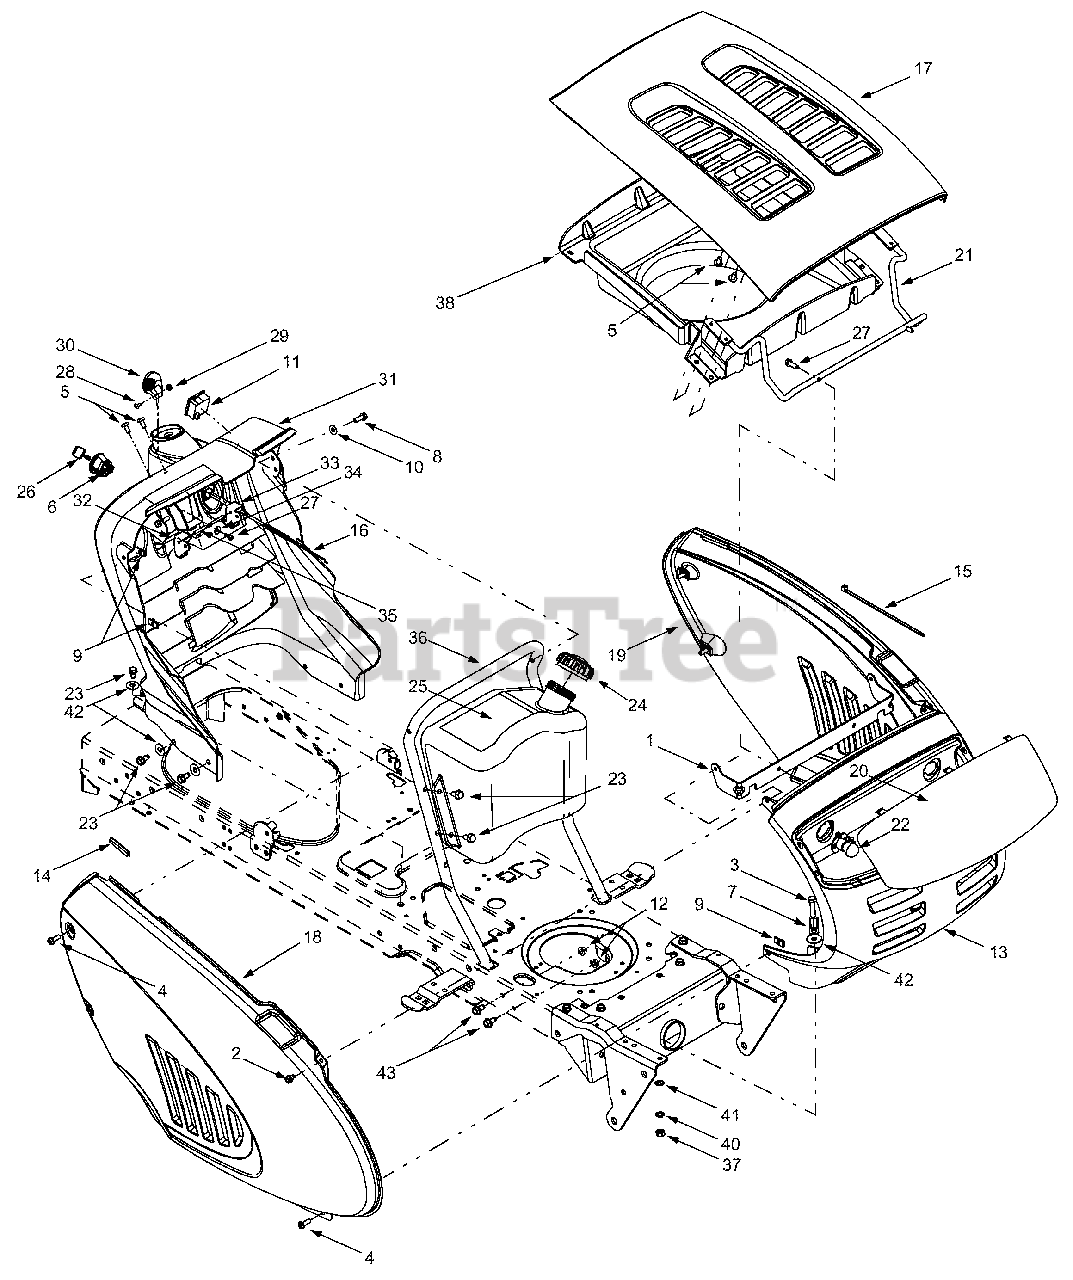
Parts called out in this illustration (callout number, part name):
2	Self-tapping Screw, 1/4-20 x .5
3	Hex Cap Screw, 5/16-18 x 1.25
4	Phillips Pan Screw, 1/4-20 x .75
5	Truss Phillips Screw, 1/4-20 x .625
6	Ignition Switch
7	Clamp, 9/16
8	Self-tapping Screw, 1/4-20 x .75
9	U-type Speed Nut, 1/4-20
10	Bell Washer, .265 x .75 x .062
11	Systems Indicator Monitor
12	Hex Nut, 5/16-18
13	Grille (9-style)
14	Trim Strip, 4
15	Cable Tie, 3/16 x .05 x 7.4
16	Choke Knob/Cable (Model G609G)
21	Hood Hinge Rod
22	Headlight Assembly
23	Self-tapping Screw, 5/16-18 x .625
24	Fuel Cap
25	Fuel Tank, Three-gallon (Model G609G)
26	Ignition Key w/ plastic cover
27	Self-tapping Screw, 1/4-15 x .75
28	Truss Phillips Screw, #8-32 x .375
29	Hex Nut, #8-32
30	Throttle Control Knob
31	Dash Panel, 8/9-style, Manual PTO
32	Cruise Control Button
33	Parking Brake Button
34	Flat Washer, 9/32 x 1/2 x 1/16
35	Brake/Cruise Pivot Rod
38	Hood Plenum (Model G609G)
40	Lock Washer, 5/16
41	Speed Nut, .3125
42	Flat Washer, .349 x 1.0 x .063
43	Screw, 5/16-18 x .875 (Grade 5)
